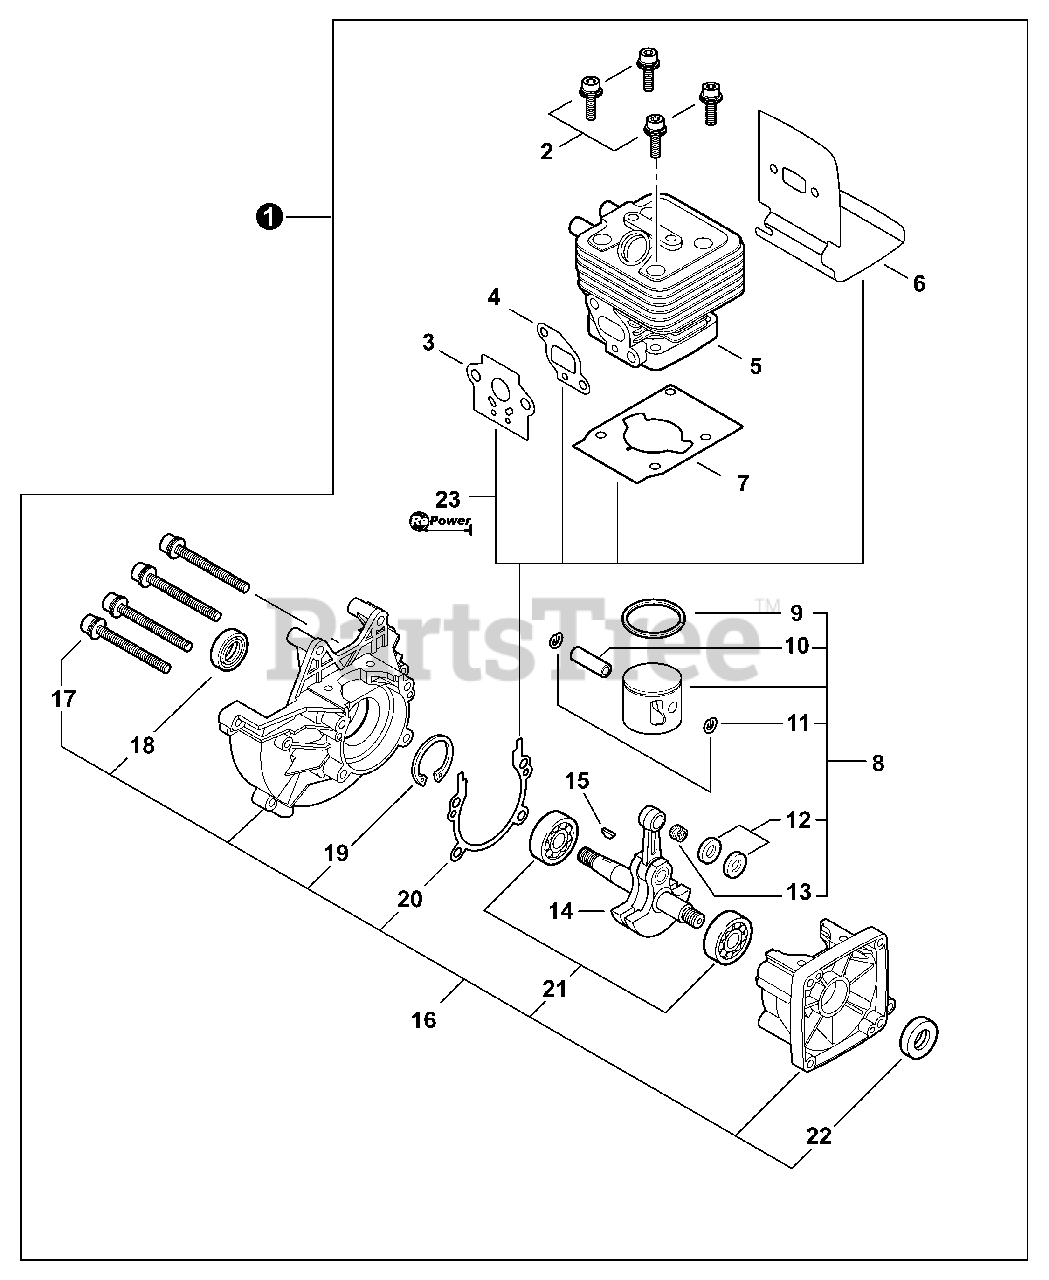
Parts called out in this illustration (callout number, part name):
1	SHORT BLOCK -- SB1091
2	SCREW - 5×25
3	GASKET, INTAKE
4	GASKET, INTAKE
5	CYLINDER
6	SHIELD, EXHAUST
7	GASKET, CYLINDER
8	PISTON KIT
9	RING, PISTON
10	PIN, PISTON
11	RING, RETAINING
12	SPACER, PISTON
13	BEARING, NEEDLE
14	CRANKSHAFT ASY
15	KEY, WOODRUFF
16	CRANKCASE KIT
17	SCREW - 5×28
18	SEAL, OIL
19	RING, RETAINING - 32
20	GASKET, CRANKCASE
21	BEARING, BALL - 6201
22	SEAL, OIL - 12
23	GASKET KIT - REPOWER
